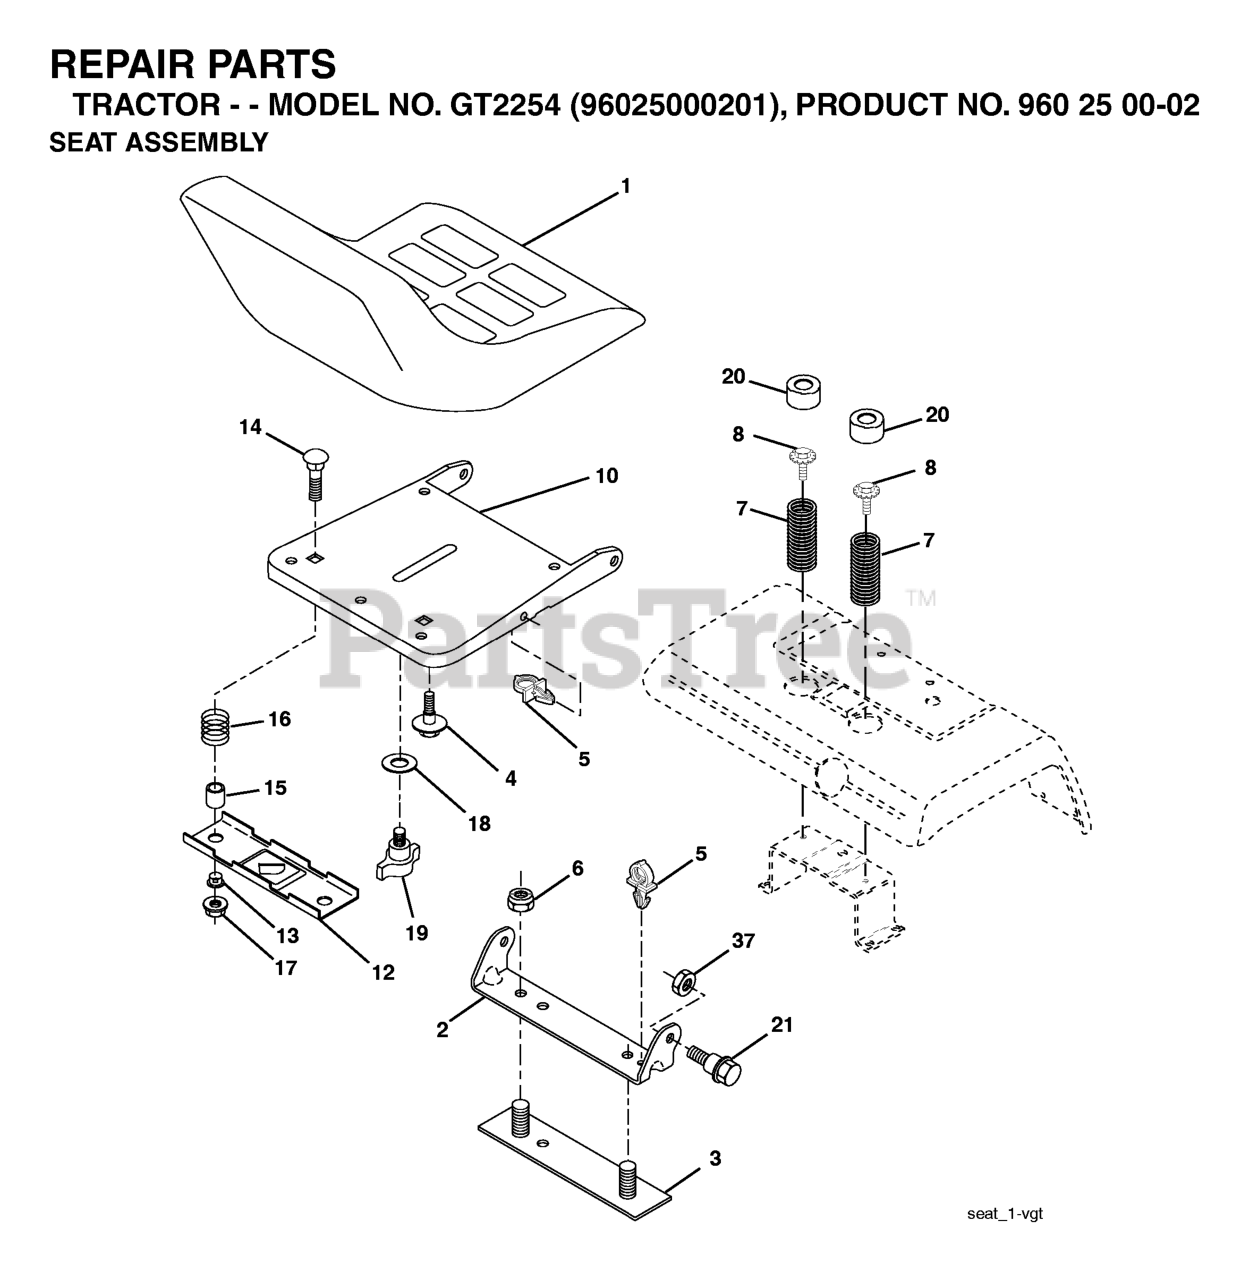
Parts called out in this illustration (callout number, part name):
1	RP SEAT
2	SEAT PIVOT BRKT
3	STRAP
4	BOLT,SHOULD
6	NUT
7	SPRING COMPRESSION
8	BOLT.5/16-18UNCX3/4 W/SEMS.BLK
10	PAN SEAT
12	BRKT.MNTNG.SWITCH.SEAT.BLACK
14	BOLT.ROUND.HEAD.SQUARE.NECK
15	SPACER SPLIT 28X.96
17	NUT T
19	KNOB.SEAT.ADJ.WINGNUT
20	CAP SPRING
21	BOLT.SHOULDER.5/16-18
22	LOCKNUT
37	NUT.71038.31-18.HEX.NYLOCK
